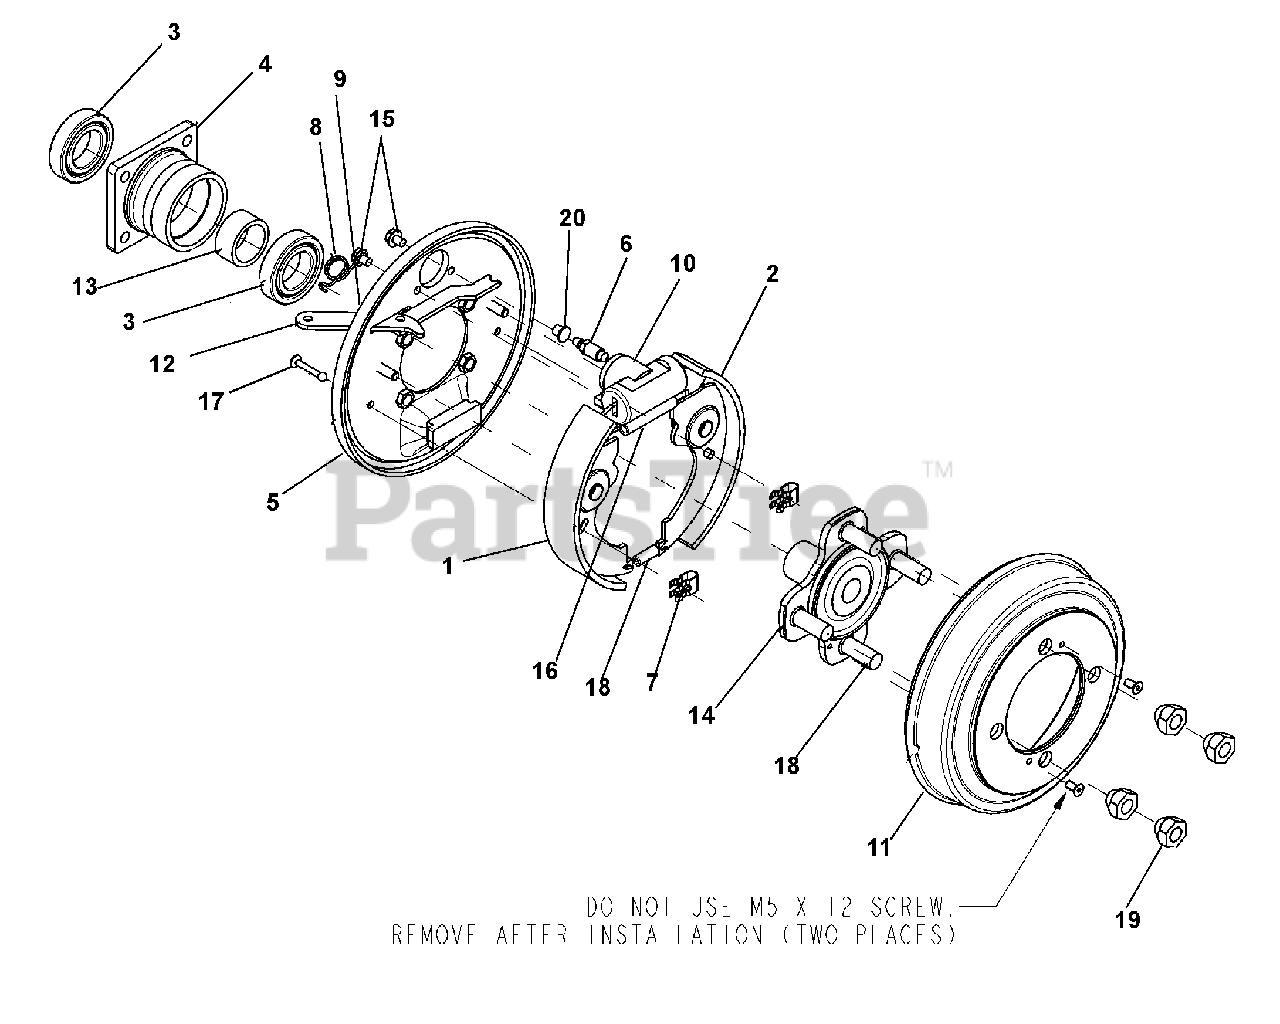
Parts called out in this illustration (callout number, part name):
1	LEFT SHOE
2	RIGHT SHOE
3	BALL BEARING
4	BEARING HOLDER HUB
5	BRAKE SHOE DISC RIGHT HAND
6	BLEEDER SCREW
7	SHOES LOCKING SPRING
8	RIGHT SPRING/HAND BRAKE LEVER
9	LEFT SPRING/HAND BRAKE LEVER
10	HYDRAULIC CYLINDER
11	DRUM
12	RIGHT LEVERS SET
13	CMX SPACER
14	BRAKE FLANGE HUB WITH STUDS
15	SCREW M6 X 40
16	UPPER RETURN SPRING
17	SPRING PIN
18	LOWER RETURN SPRING
19	WHEEL NUT .500-20 YZ
20	BLEEDER CAP
F178	BRAKE SHOE DISC LEFT HAND
F177	LEFT LEVERS SET
